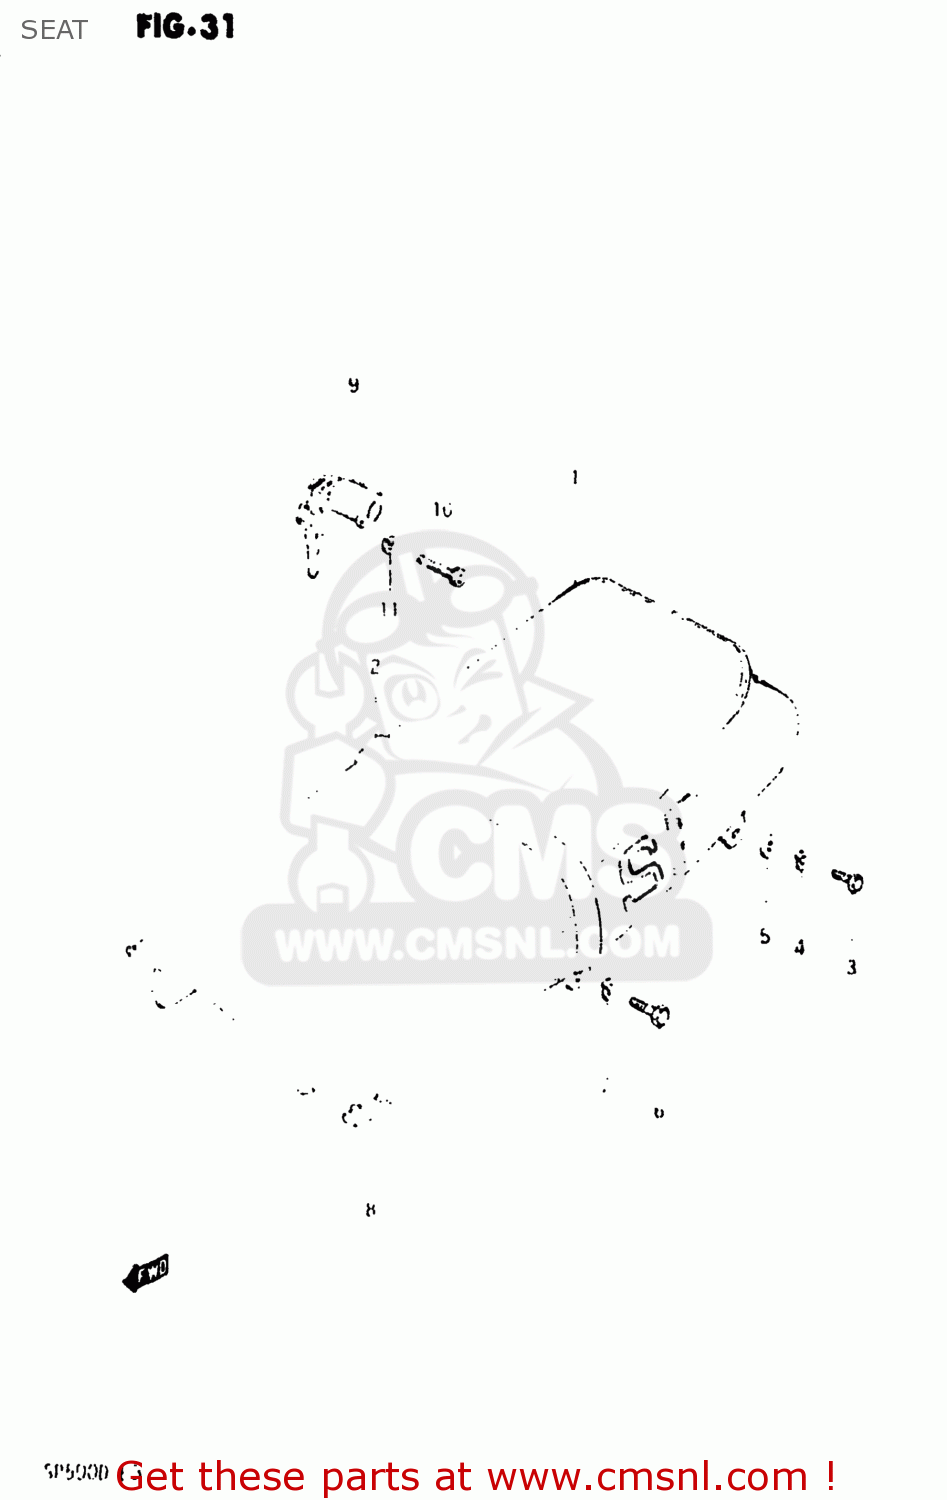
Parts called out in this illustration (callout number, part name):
1	SEAT ASSEMBLY
2	BAND,SEAT
3	BOLT
4	WASHER,LOCK,8.
5	WASHER
6	BOLT
7	LOCK WASHER
8	CUSHION
9	LOCK SET,HELMET
10	SCREW
11	LOCK WASHER
